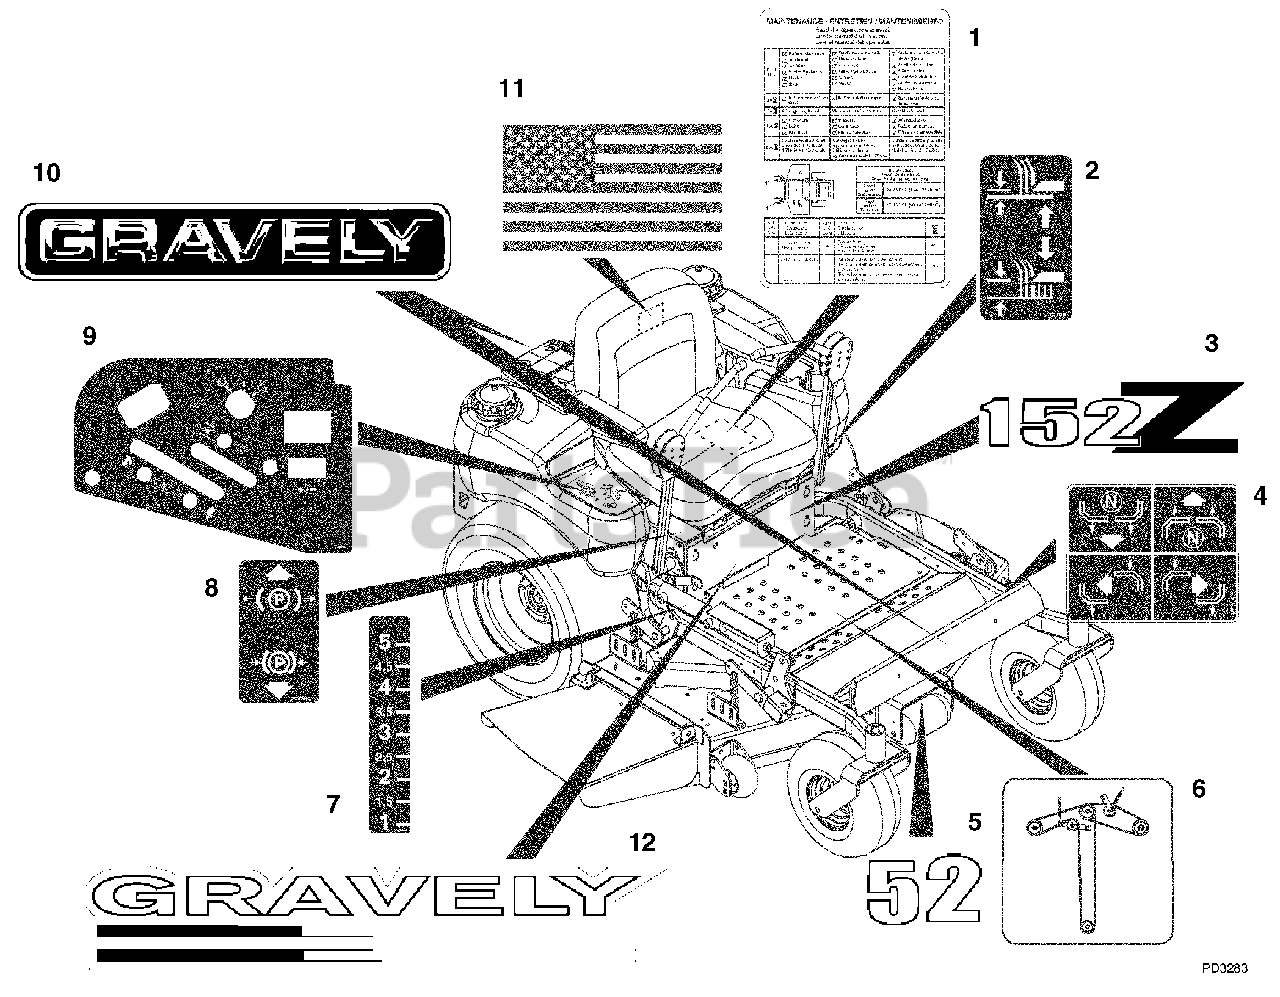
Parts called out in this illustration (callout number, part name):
1	Decal, Service Instructions
2	Decal, Lift Lever
3	Decal, PM 152Z (044, 054)
3	Decal, PM 144Z (042)
3	Decal, PM 148Z (043)
3	Decal, PM 160Z (051, 055)
4	Decal, Instructional Steering
5	Decal, 52 (044, 054)
5	Decal, 44 (042)
5	Decal, 48 (043)
5	Decal, 60 (051, 055)
6	Decal, Belt Diagram
7	Decal, Height of Cut
8	Decal, Parking Brake Lever
9	Decal, Control Panel
10	Decal, 15" Gravely Logo
11	Decal, American Flag
12	Decal, ZT Hood
